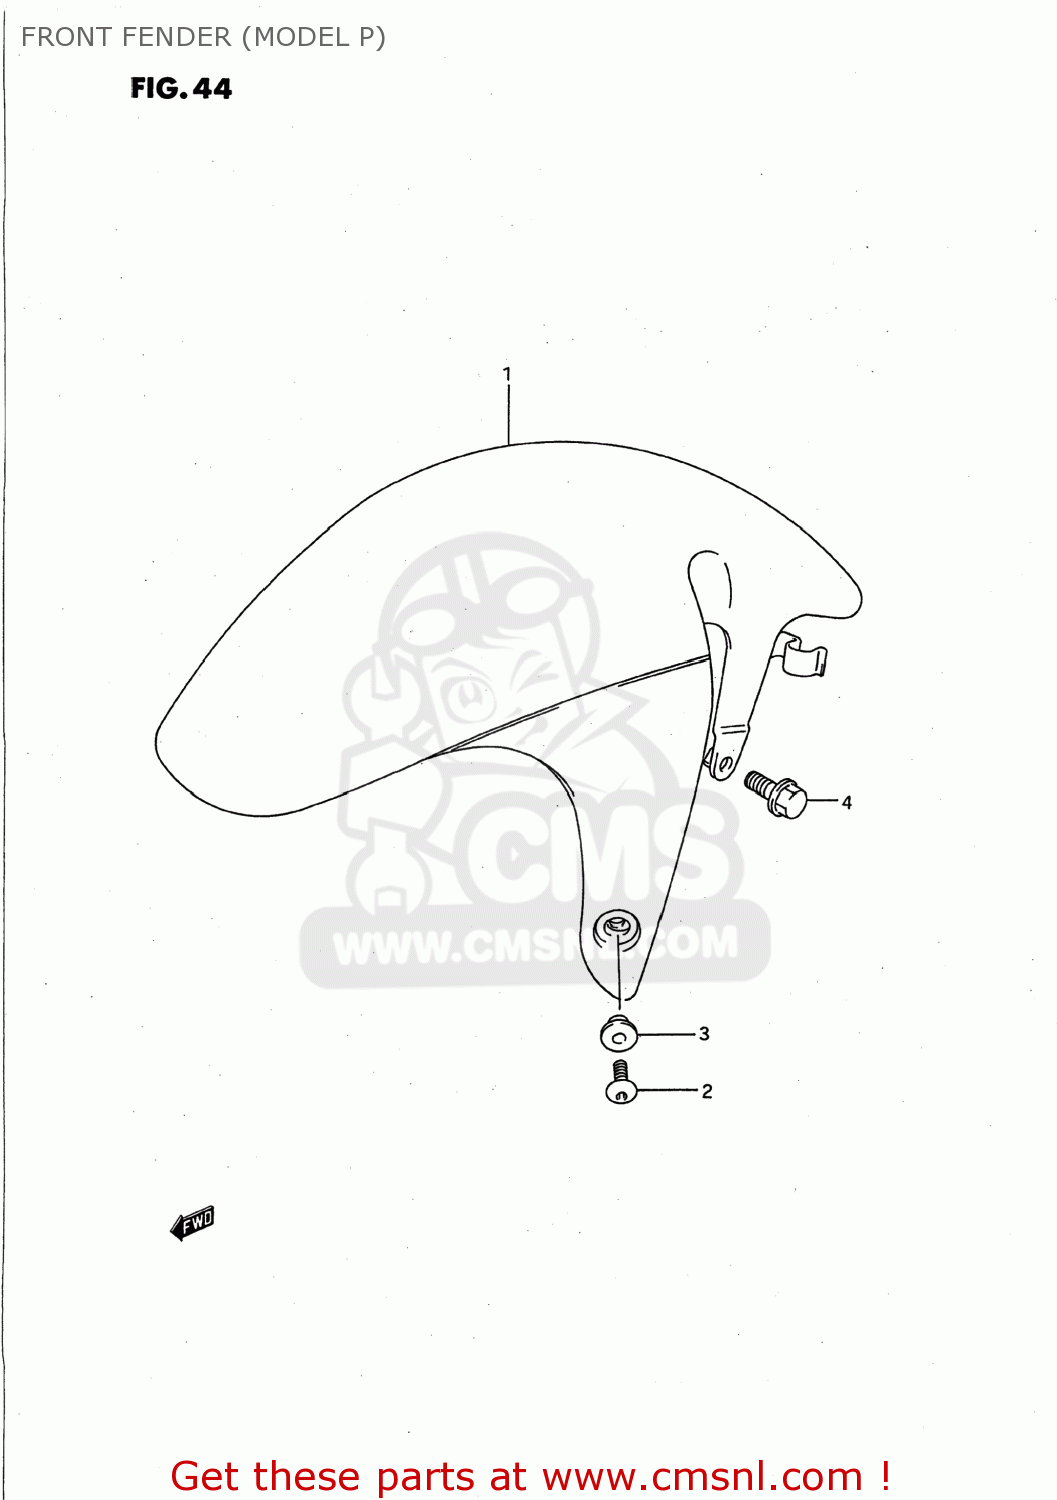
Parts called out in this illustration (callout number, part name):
1	FENDER,FRONT
2	SCREW(6X16)
3	WASHER(6.3X16X1.5)
4	BOLT, LOWER
